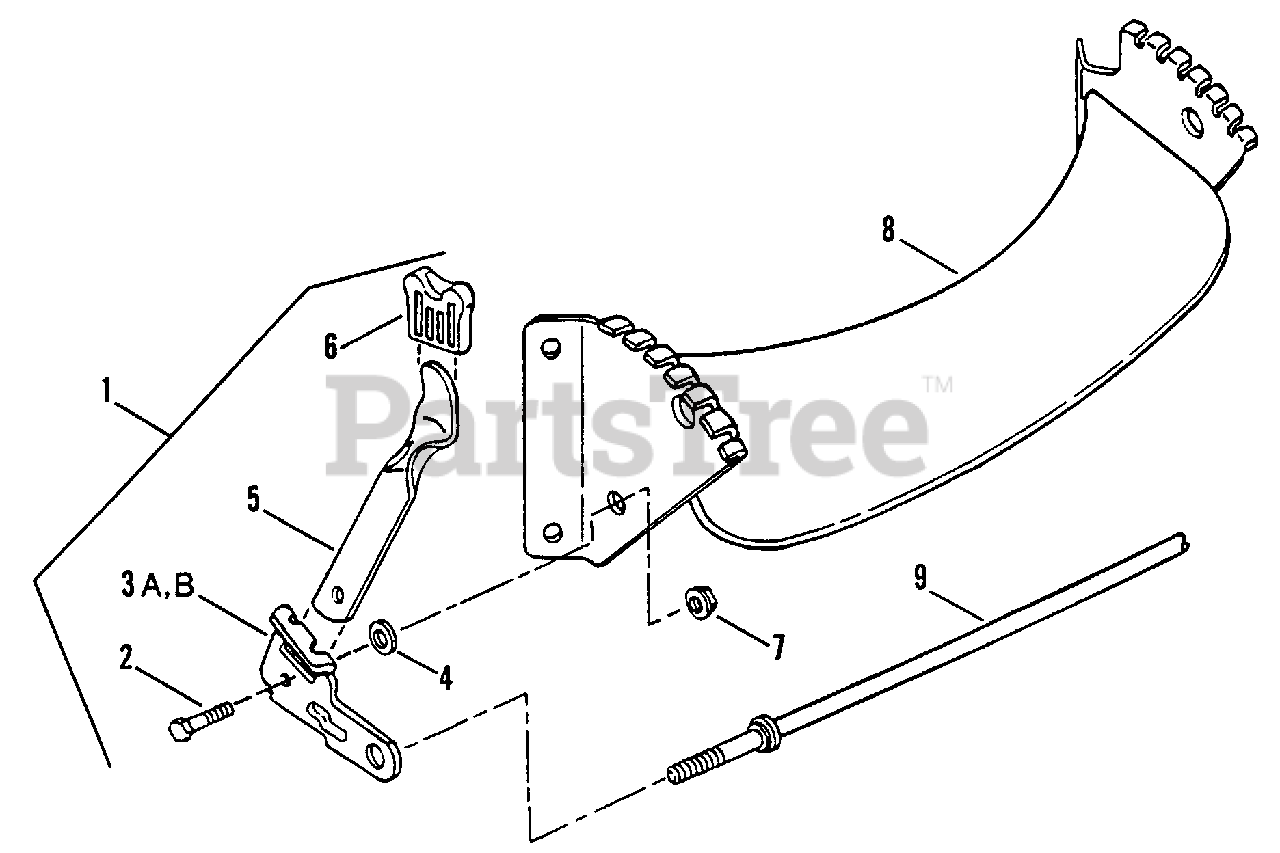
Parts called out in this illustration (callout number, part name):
1	ASSEMBLY, Arm (Right Wheel)
2	BOLT, 5/16-18 x 3/4" Shoulder
3A	ARM, Right Wheel (Round Hole)
3B	ARM, Left Wheel (Square Hole)
4	RETAINER, 5/16 Bolt
5	LATCH, Height
6	GRIP, Latch
7	NUT, 5/16-18 Hex Flange Lock, Grade 5
8	BRACKET, Front Wheel
9	AXLE
